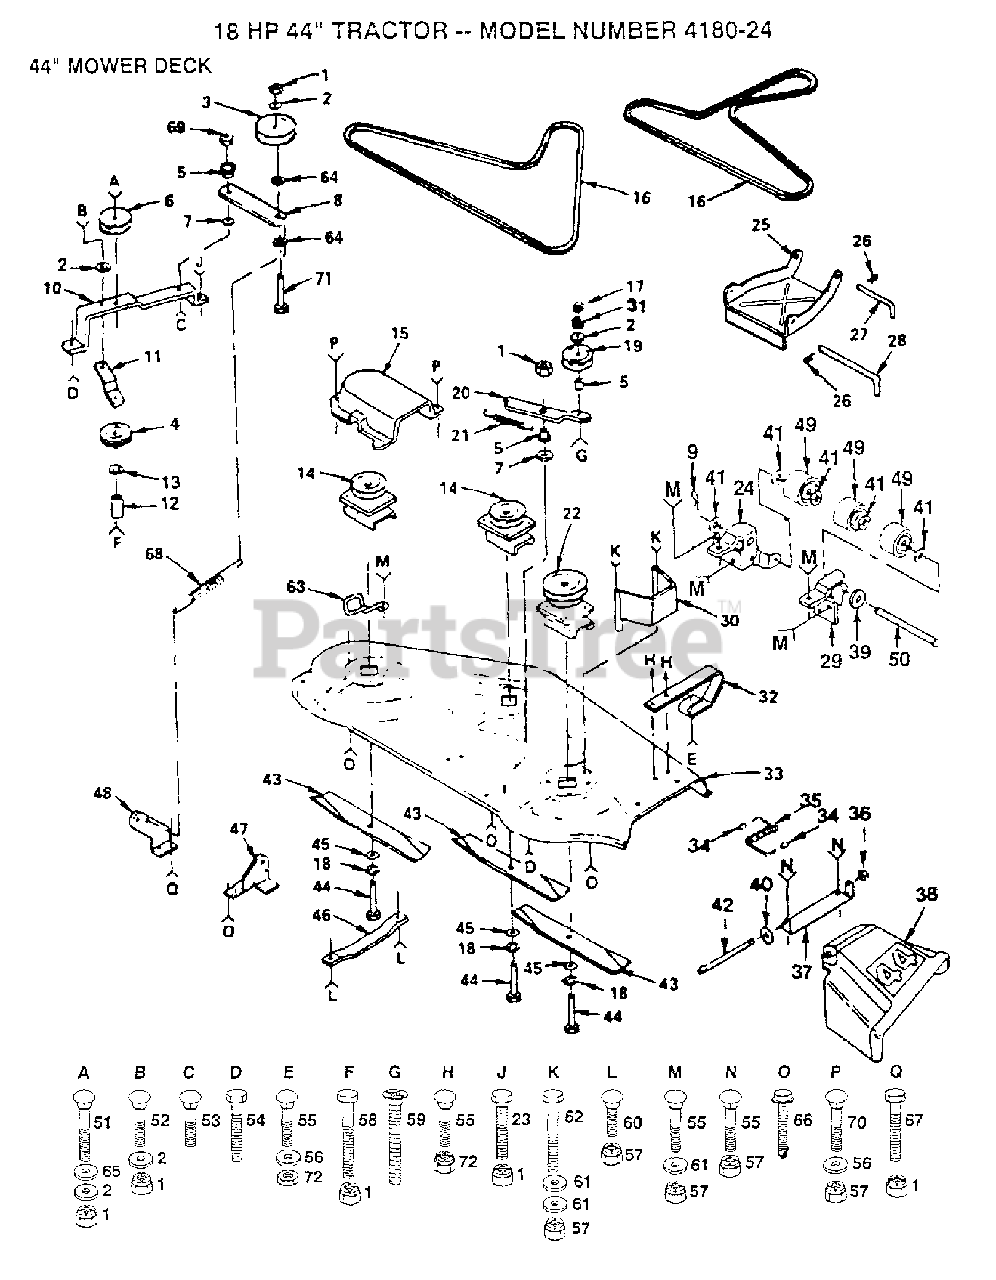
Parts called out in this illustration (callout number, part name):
1	LOCKNUT
3	PULLEY IDLER
4	IDLER-FLAT T
5	SPACER RETAINER
6	IDLER-INSIDE T
7	WASHER, WEAR LT (1 2)
8	ARM IDLER
9	COTTER PIN
10	BAR-SUPPORT YT
11	BRACE-IDLER YT
14	JACKSHAFT.ASM.
15	GUARD YT
16	V-BELT T
17	NUT.HEX.3/8-16UNC
19	IDLER.FLAT.GTV
20	ARM-IDLER YT
21	SPRING T
22	JACKSHAFT YT
23	BOLT
24	BRACKET LH YTH
25	LINK,PARALLEL
26	SPRING.RETAINER
27	ROD,FRT PARALL LT
28	HINGE PIN T
29	BRACKET RH YTH
30	GUARD BELT HYT
31	WASHER, LOCK 3/8
32	Poulan TBD
33	HOUSING
34	CAP-SLEEVE LT
35	DEFLECTOR SPRG T
36	NUT PUSH M
38	DEFLECTOR SHIELD
39	WASHER
40	WASHER
42	ROD-HINGE T
43	BLADE
44	BOLT.3/8-24X1-1/2
45	WASHER
46	RUNNER LH
47	BRKT SUSP REAR RH
49	ROLLER T
50	PIVOT PIN T
51	BOLT
55	BOLT
56	WASHER
57	LOCKNUT
59	SCREW YT
60	BOLT
61	WASHER M
63	BELT RETIANER
64	WASHER
65	WASHER
68	SPRING.EXT.8.5"
69	LOCKNUT
70	BOLT.5/16-18.
71	BOLT
72	Lock Nut
